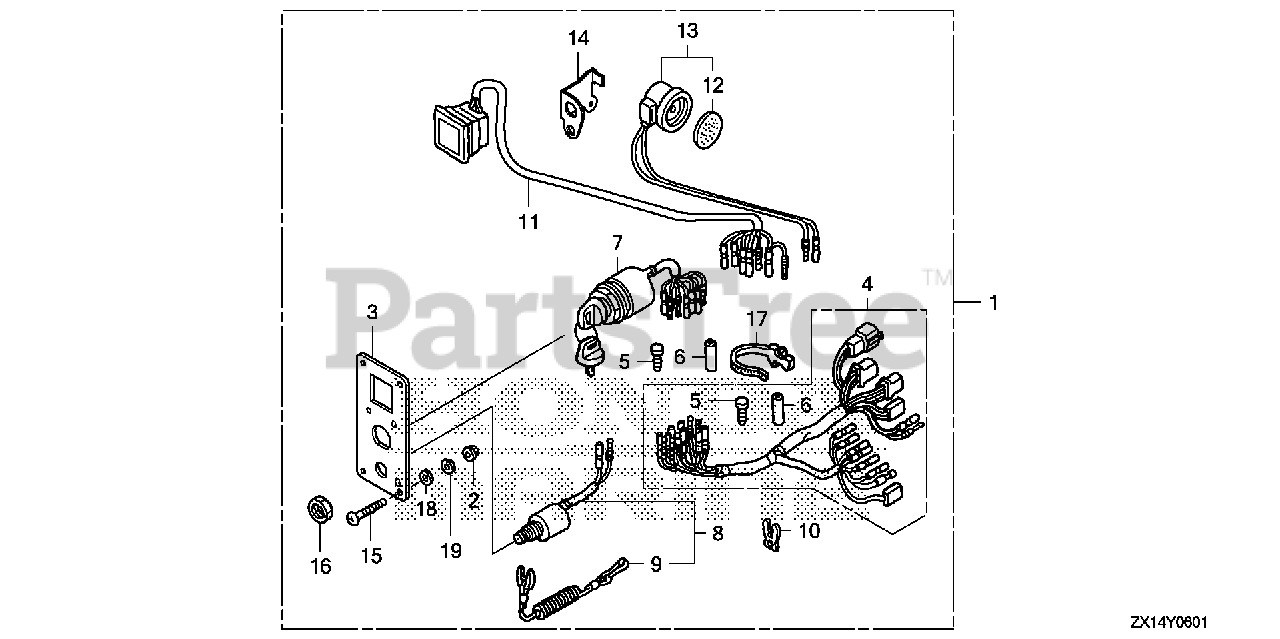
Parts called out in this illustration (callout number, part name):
1	PANEL KIT, SWITCH (4-LED)
2	NUT, FLANGE (5MM) DUAL QTY = (8) (SINGLE)
3	PANEL, CONTROL
4	HARNESS ASSY., SWITCH PANEL
5	PLUG, CONNECTOR (INNER) (TROLLING CONTROL)
6	PLUG, CONNECTOR (OUTER) (ENGINE NO.)
7	SWITCH ASSY., COMBINATION (SINGLE) (DUAL)
8	SWITCH ASSY., EMERGENCY STOP
9	WIRE, EMERGENCY (SINGLE) (DUAL)
10	CLIP, EMERGENCY LOCK
11	LAMP ASSY., INDICATION (4-LED)
12	PLATE, TURN SIGNAL BUZZER DUAL QTY = (2) (SINGLE)
13	BUZZER, WARNING DUAL QTY = (2) (SINGLE)
14	BRACKET, BUZZER
15	SCREW, PAN (5X40) DUAL QTY = (8) (SINGLE)
16	NUT, HEX. (16MM) DUAL QTY = (2) (SINGLE)
17	BAND, WIRE HARNESS (150MM) (NATURAL) DUAL QTY = (2) (SINGLE)
18	WASHER, PLAIN (5MM) DUAL QTY = (8) (SINGLE)
19	WASHER, SPRING (5MM) DUAL QTY = (8) (SINGLE)
